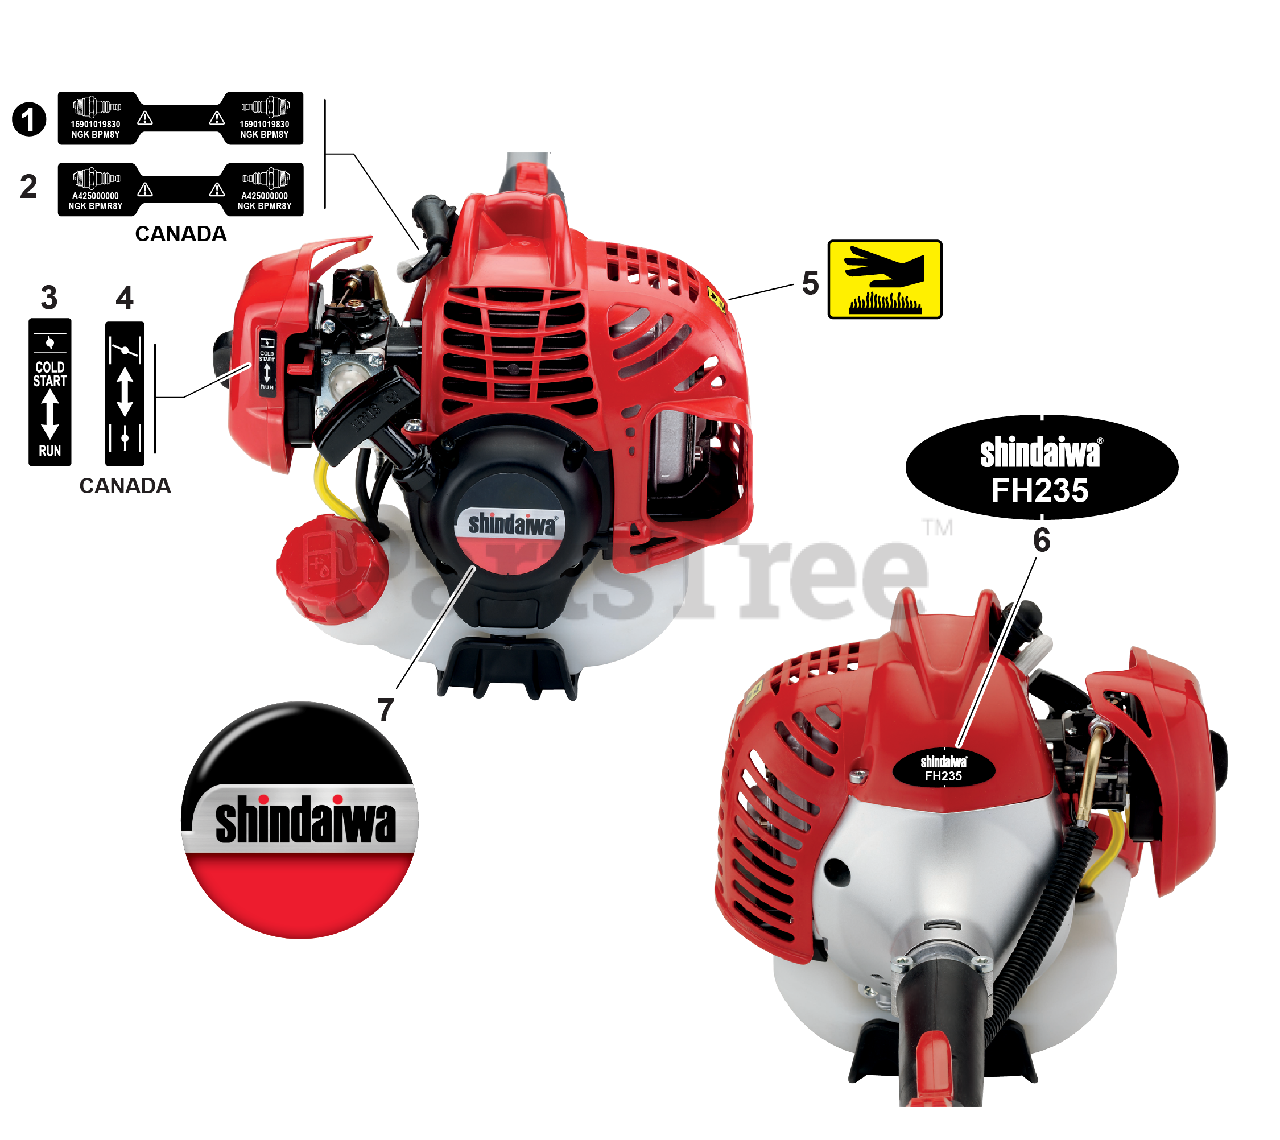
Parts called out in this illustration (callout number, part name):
1	LABEL - SPARK PLUG -- BPM-8Y
2	LABEL - SPARK PLUG -- BPMR-8Y
3	LABEL - CHOKE
4	LABEL - CHOKE
5	LABEL - CAUTION -- HOT
6	LABEL - MODEL
7	LABEL - SHINDAIWA
